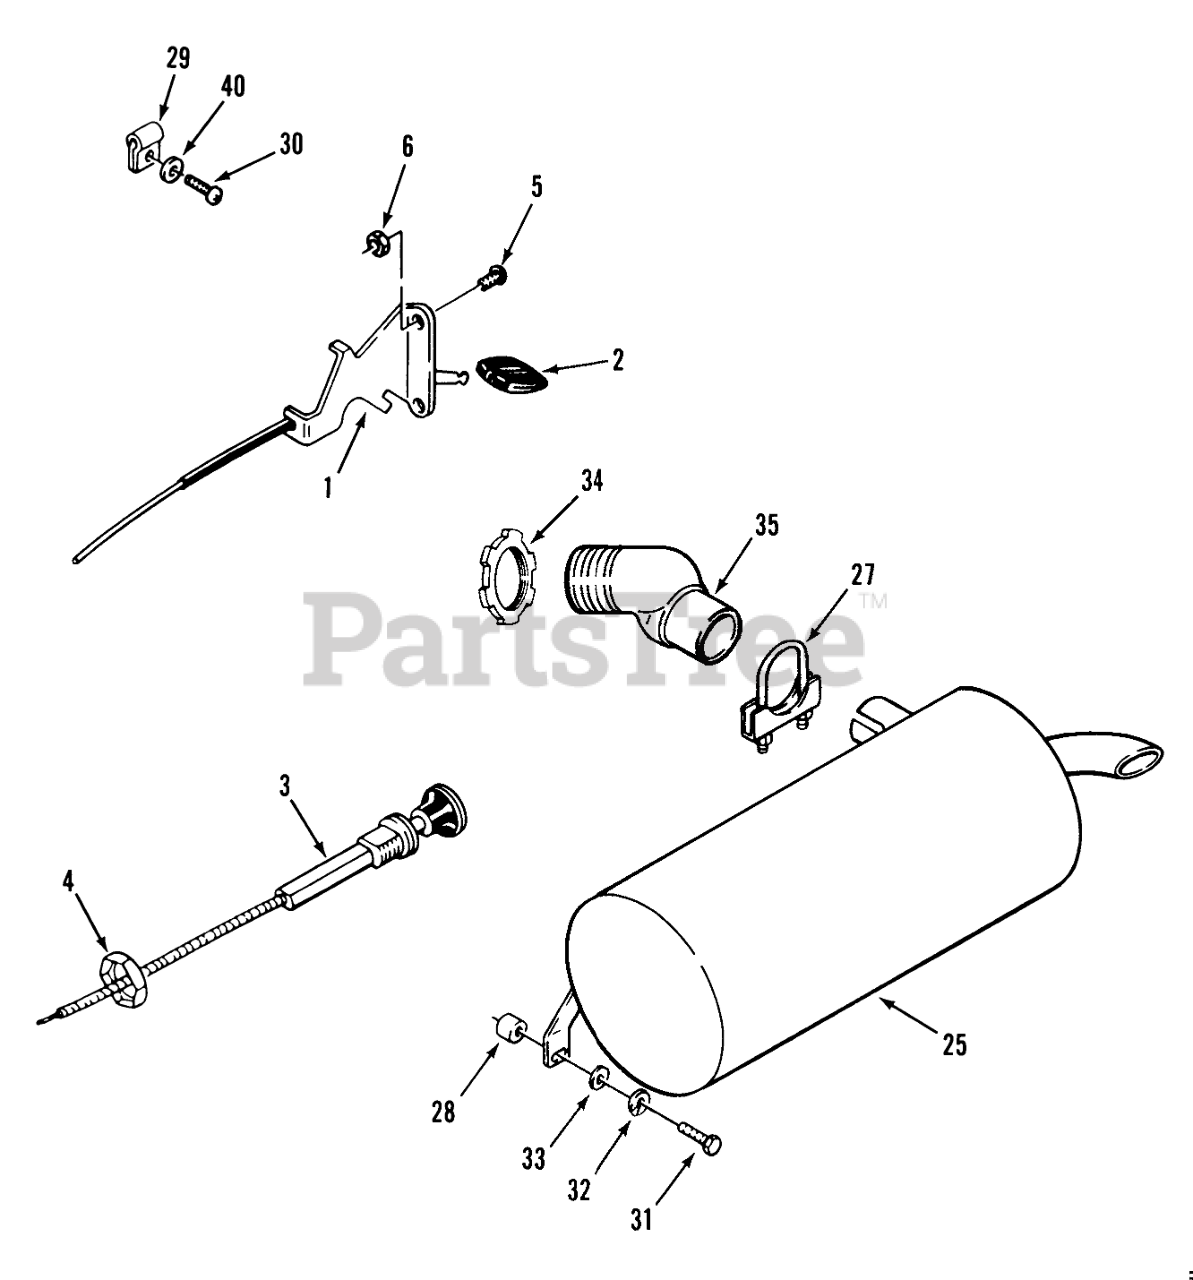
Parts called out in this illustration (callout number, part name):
1	Throttle Control 310, 312, 414
1	CONTROL-THROTTLE
2	KNOB-THROTTLE
3	CONTROL CHOKE
3	CONTROL-CHOKE
4	NUT-HEX PALNUT
5	SCRW-PHC
6	Nut
25	Muffler
27	CLAMP-1 1/2
28	SPACER
30	Screw
31	Bolt
32	Lockwasher
33	WASHER 5/16 SAE
34	Nut-Lock
35	Elbow
40	Washer
